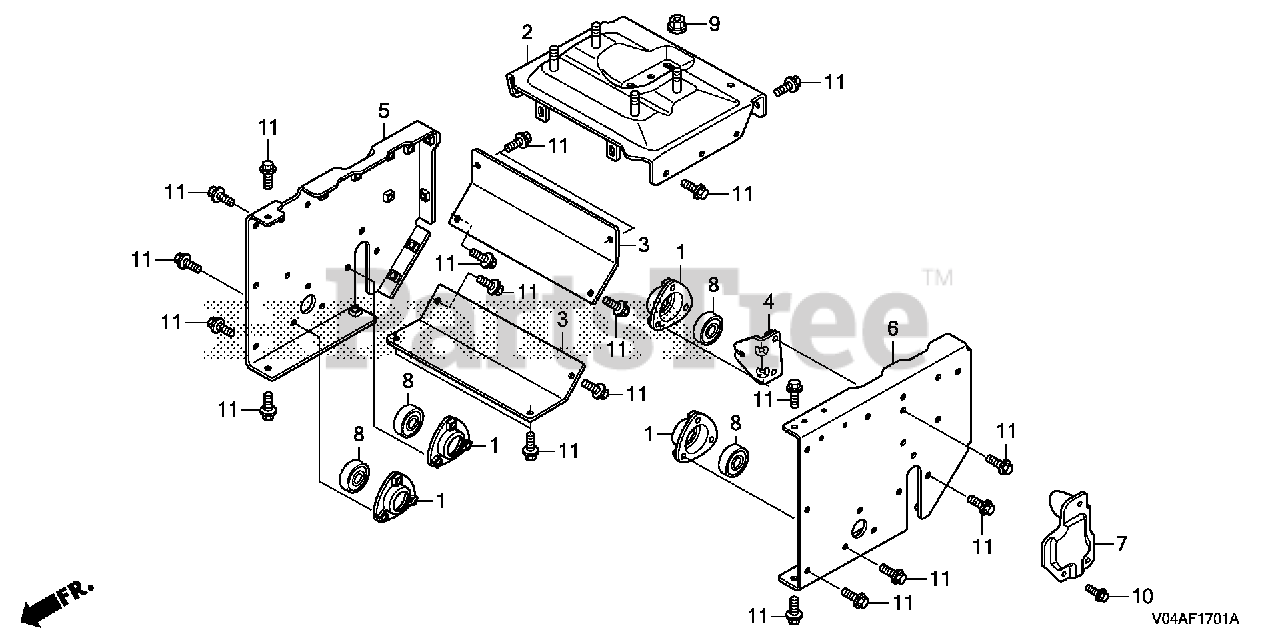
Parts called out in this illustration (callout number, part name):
1	HOLDER, BEARING
2	BED, ENGINE
3	STAY A, ENGINE BED
4	STAY, CHANGE CABLE
5	STAY, R. ENGINE BED
6	STAY, L. ENGINE BED
7	BRACKET, MOTOR COVER
8	BEARING, RADIAL BALL (6203-19.05)
9	NUT, FLANGE (8MM)
10	BOLT, FLANGE (6X12)
11	BOLT, FLANGE (8X16)
